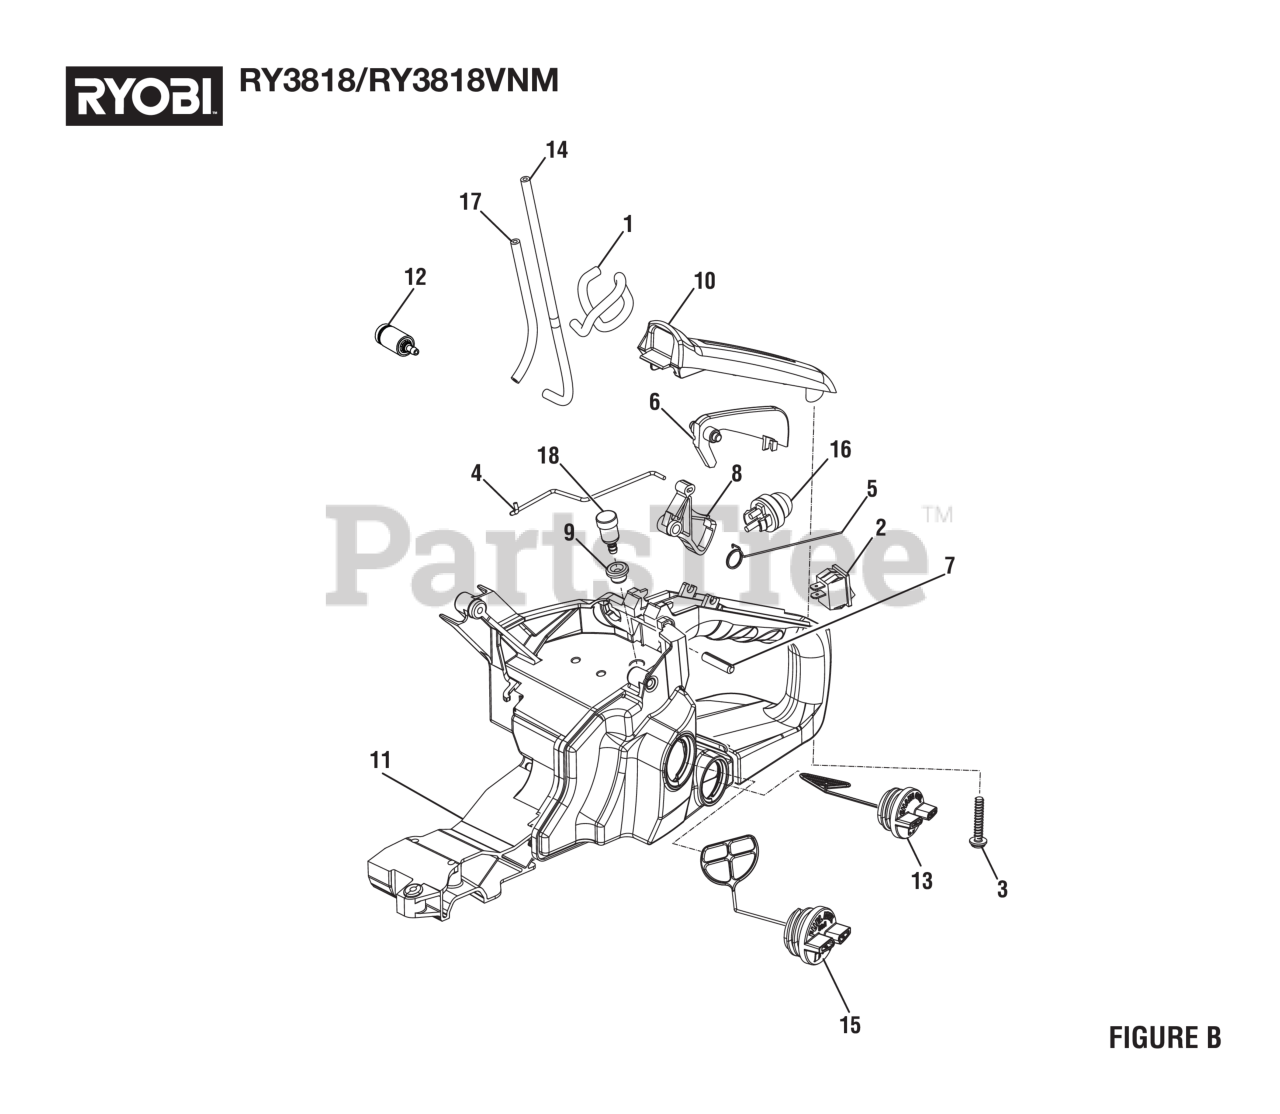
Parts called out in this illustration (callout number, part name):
1	Fuel Hose (Primer Assembly to Carburetor, 160 mm)
3	Screw (M5 x 27 mm, T25 Torx Pan Hd.)
4	Throttle Rod.
5	Throttle Spring
6	Safety Rock Arm
7	Spring Pin
8	Throttle Trigger
10	Grip Cover
11	Rear Handle Assembly
12	Fuel Filter Assembly
13	Oil Cap Assembly
14	LP-1500 Tubing (205.00 mm)
15	Fuel Cap Assembly
16	Primer Bulb
17	Fuel Hose (Primer Assembly to Tank, 153 mm)
18	Fuel Breather Assembly
